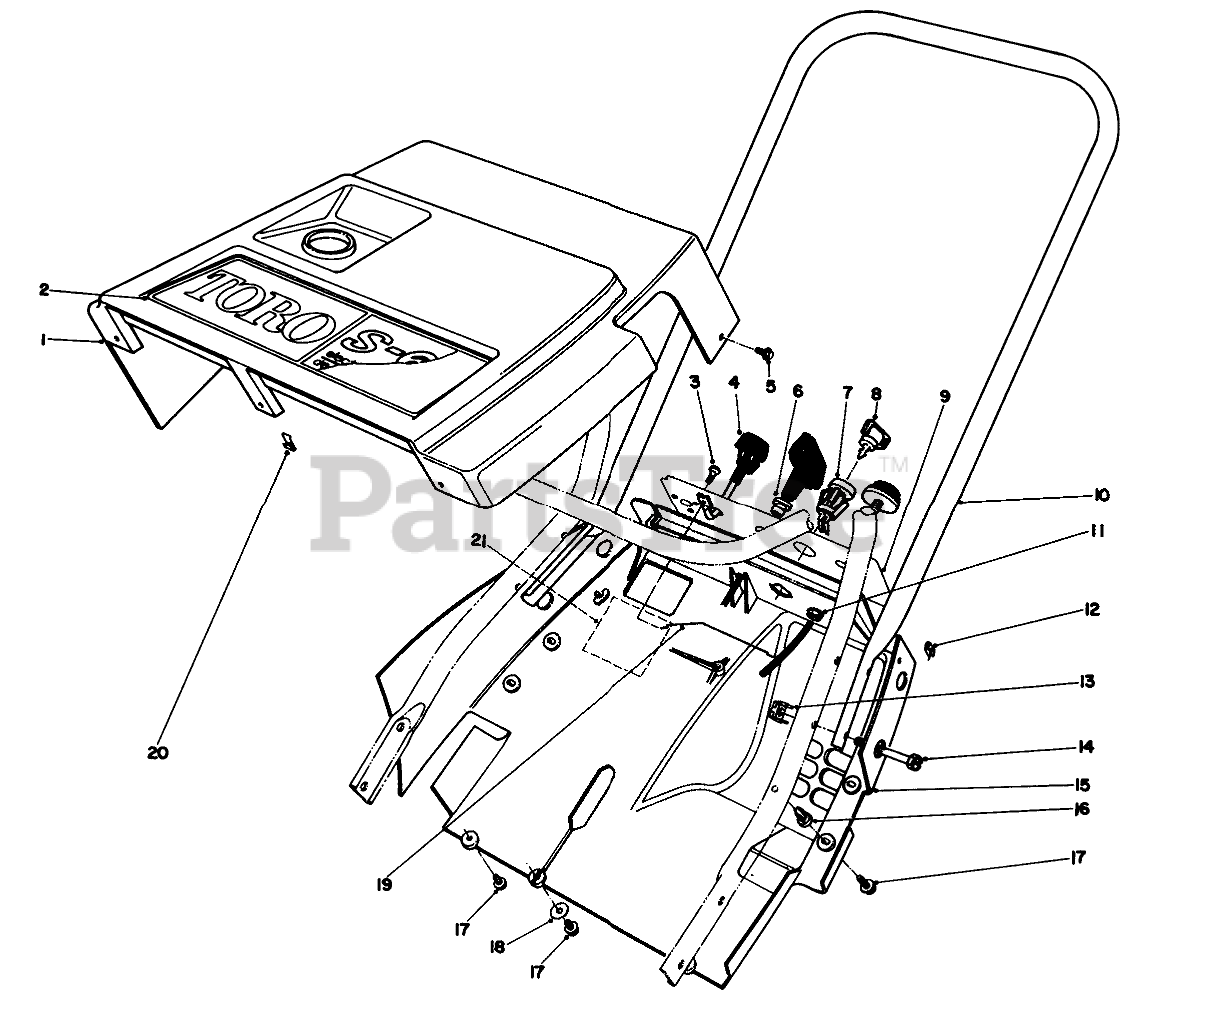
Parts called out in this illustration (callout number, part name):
1	Shroud-Upper
2	TORO DECAL
3	SCREW-PLASTITE
4	CHOKE CONTROL ASM
5	SCREW-HWHTF
6	GUIDE-ROPE, STARTER
7	SWITCH
8	KEY-IGNITION
9	CONTROL PANEL DECAL
10	UPPER HANDLE ASM
11	NUT-KEPS
13	TINNERMAN NUT
14	SCREW-HEX HD SLOT
15	LOWER SHROUD
16	Nut-Push
17	SCREW-HWHTF
18	WASHER-FLAT
19	CONTROL WIRE
20	NUT "U"
21	DECAL - CSA
